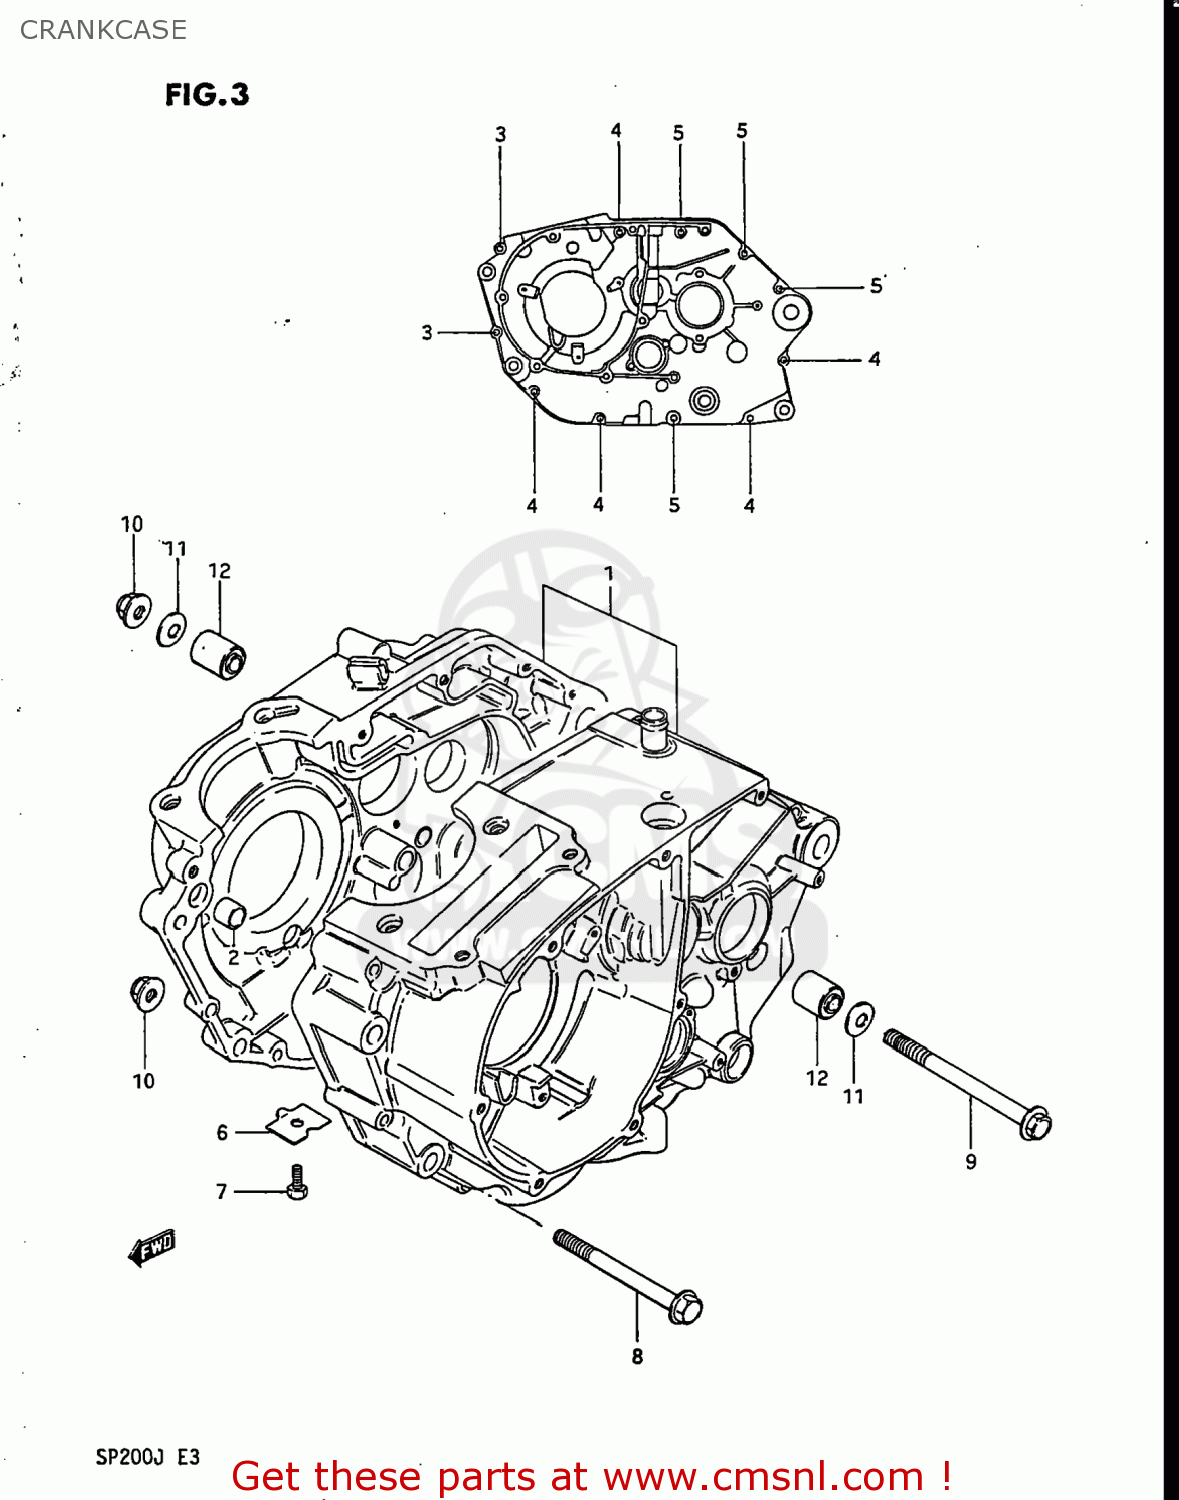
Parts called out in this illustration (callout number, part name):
1	CRANKCASE SET
2	PIN
3	BOLT
4	BOLT (6X60)
5	BOLT (6X75)
6	PLATE,OIL GALLERY PLUG
7	BOLT
8	BOLT(8X80)
9	BOLT(8X115)
10	NUT
11	WASHER
12	BUSH(8.4X18X16)
